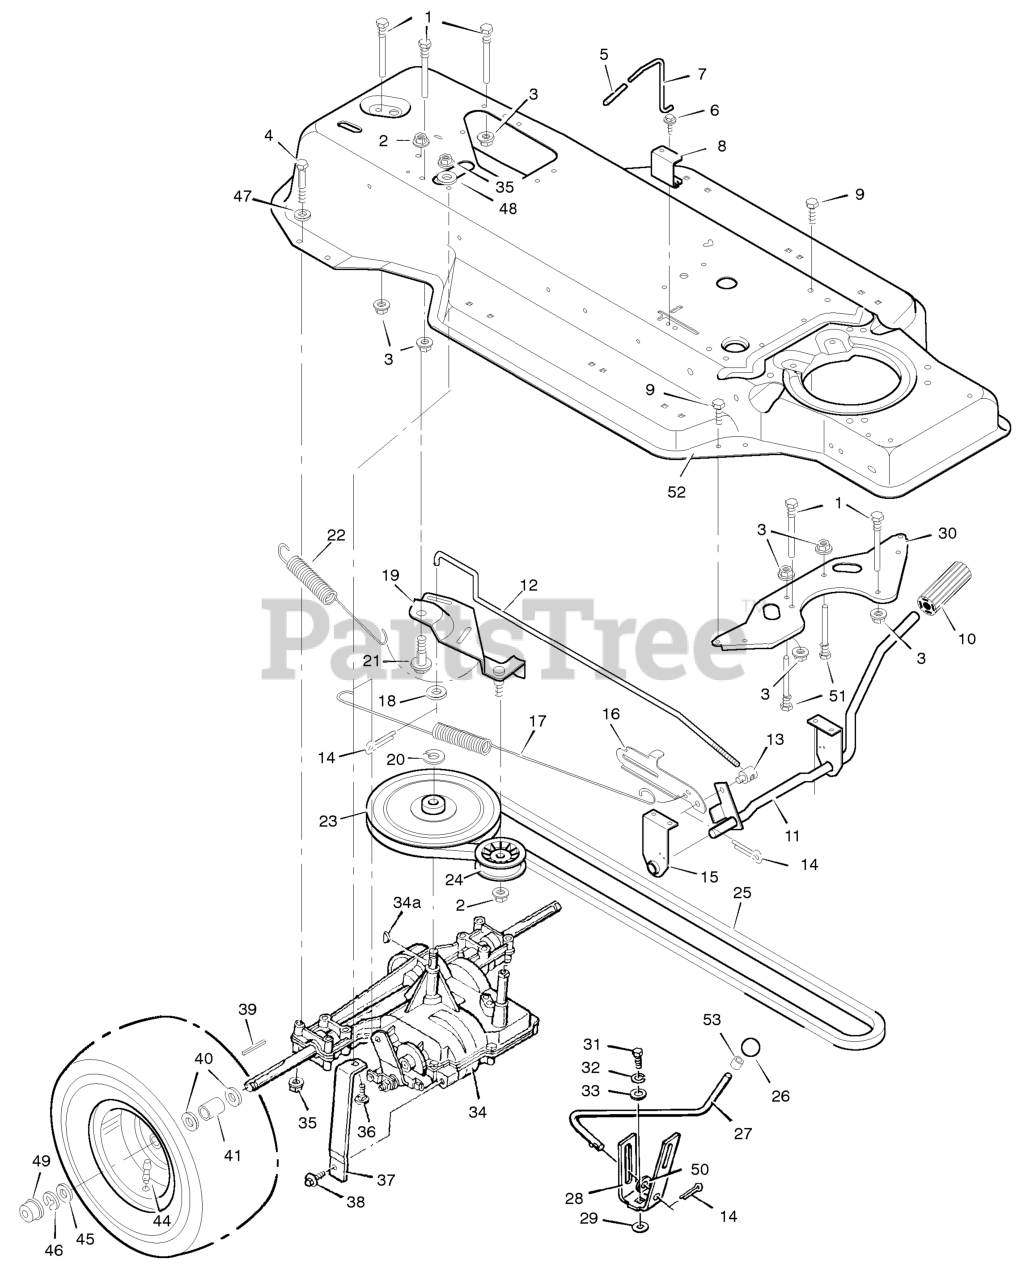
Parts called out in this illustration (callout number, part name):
1	Guide, Belt
2	Locknut, Flange
3	Nut, Flange
4	Bolt, Hex
7	Rod, Control
8	Guide, Bracket
10	Clutch and Brake Pedal
11	Lever Assembly
12	Rod, Clutch
13	Nut, Adjustable
14	Pin, Cotter
15	Bracket, Support
16	Latch, Park Brake
17	Spring, Brake Extension
18	Washer
19	Bracket Assembly, Idler
20	Ring, Retainer
21	Bolt, Shoulder
22	Spring, Drive Extension
23	Pulley, Motion Drive
24	Pulley, Backside Idler
25	Belt, Motion Drive
26	Knob, Shift Lever
27	Lever, Shift
28	Yoke, Shift
30	Plate, Belt Guide
31	Bolt, Hex
32	Lockwasher
34	Transaxle, Peerless **
34A	Woodruff Key No. 9
35	Nut, Flange
36	Bolt, Carriage
37	Support, Transaxle
39	Key, Square
41	Spacer, Transaxle
43	Wheel & Tire Assembly
44	Stem, Valve
47	Washer
49	Hub Cap
50	Washer
51	Guide, Belt
52	Frame Assembly
53	Ring, Tolerance
57	Screw
